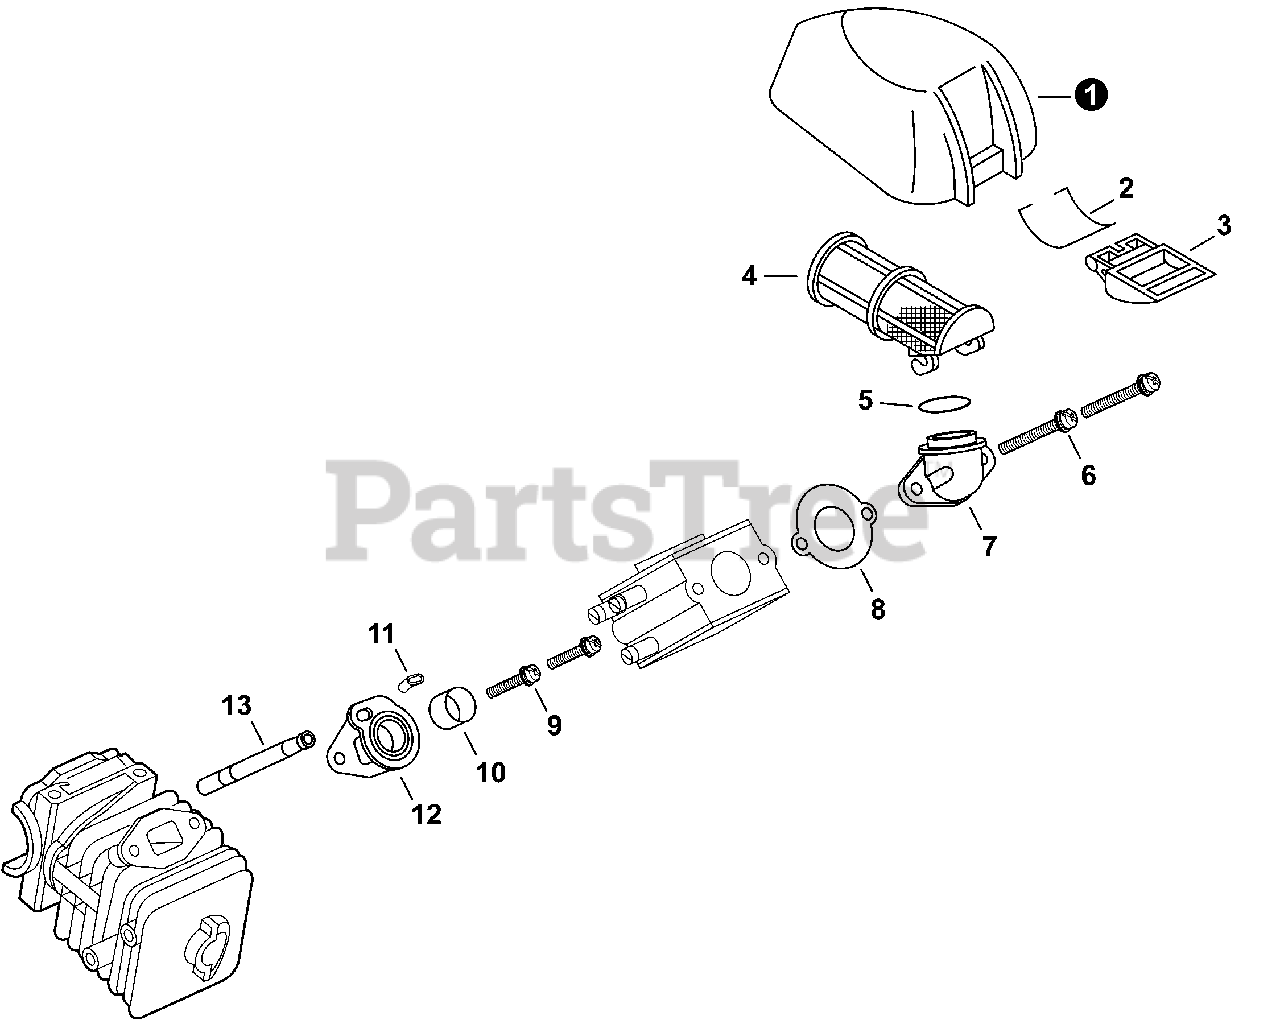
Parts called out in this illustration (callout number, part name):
1	COVER, AIR FILTER
2	RETAINER
3	LATCH, COVER
4	FILTER, AIR
6	SCREW 5×50
7	ADAPTOR, AIR FILTER
8	GASKET, INTAKE
9	SCREW 5×12
10	COLLAR 16
11	COLLAR Ø3.2×6.5
12	BELLOWS, INTAKE
13	PIPE, PULSE 3×7×65
